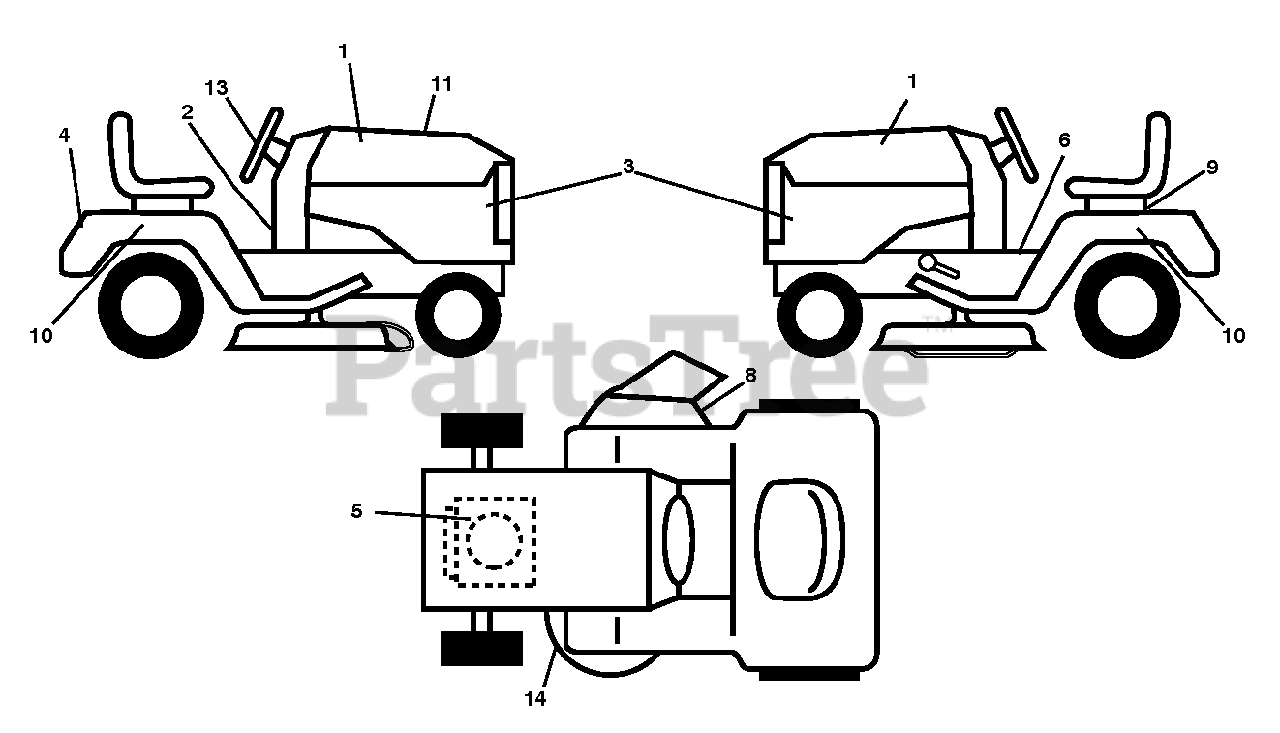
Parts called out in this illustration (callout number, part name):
1	DECAL.HOOD.POULAN.PRO.SET
2	DCL.WARNING.SPARK.IGNITION.CA
3	DECAL.REAR.FNDR.LOGO.POULAN.PR
5	DECAL.ENG.BS.22HP.INTK
6	DECAL.WARNING.2007.ENG/FR
8	DECAL.WARN.KEEP.HAND.AWAY
9	DECAL BTRY SYMBOLS
13	DECAL.STEER.WHEEL.POULAN.PRO
14	DECAL.V-BELT.SCH.42/46"MEC/ELE
